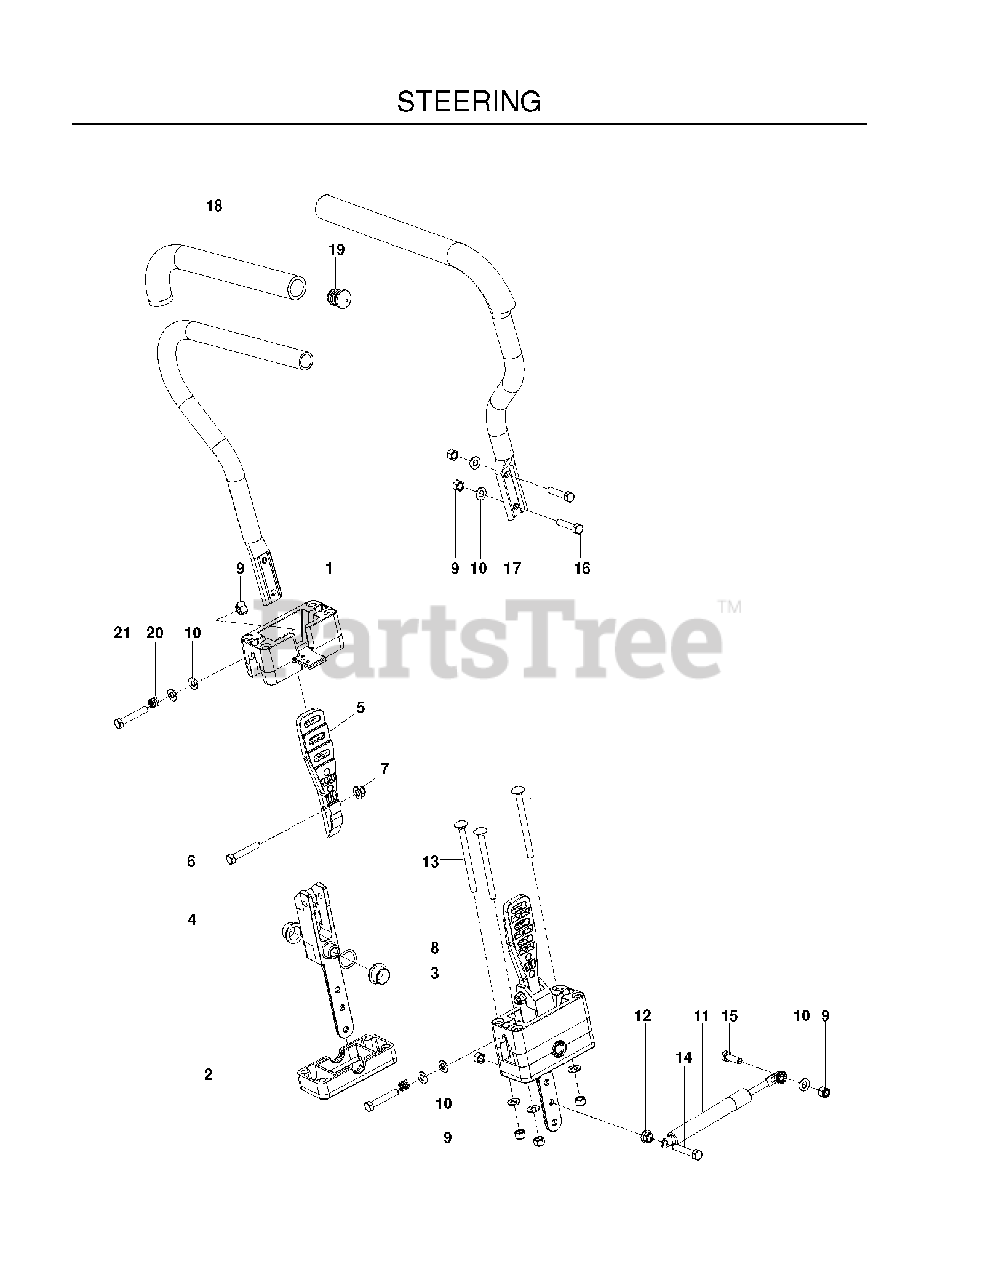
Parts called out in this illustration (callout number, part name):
1	BLOCK, UPPER
2	BLOCK, LOWER
3	BEARING, FLANGE
4	PIVOT.SECTION.DRIVE.CONTROL
5	MOUNT, DR CNTRL HANDLE
6	HCS 5/16C X 1 3/4
7	5/16-18 NYLOC FLANGE NUT
8	WASHER, .825 X 1.087, WAVE
9	NUT 5/16 NYLOC
10	FLAT WASHER 5/16 SAE
11	DAMPENER
12	NUT 5/16C WHIZ
13	RHSNB 5/16-18 X 4 GR 5 ZD
14	HCS 5/16-18X1-3/4 TPBLT
15	HCS 5/16C X 1
16	CAPSCREW 5/16 X 1/1/2 HEX HEAD
17	LEVER.DRIVE.W/GRIP
18	GRIP, FOAM (GROUND) 15
19	END PLUG 15/16` (BLACK)
21	HCS 5/16-18 X 2 TPBLT GR 5 ZD
